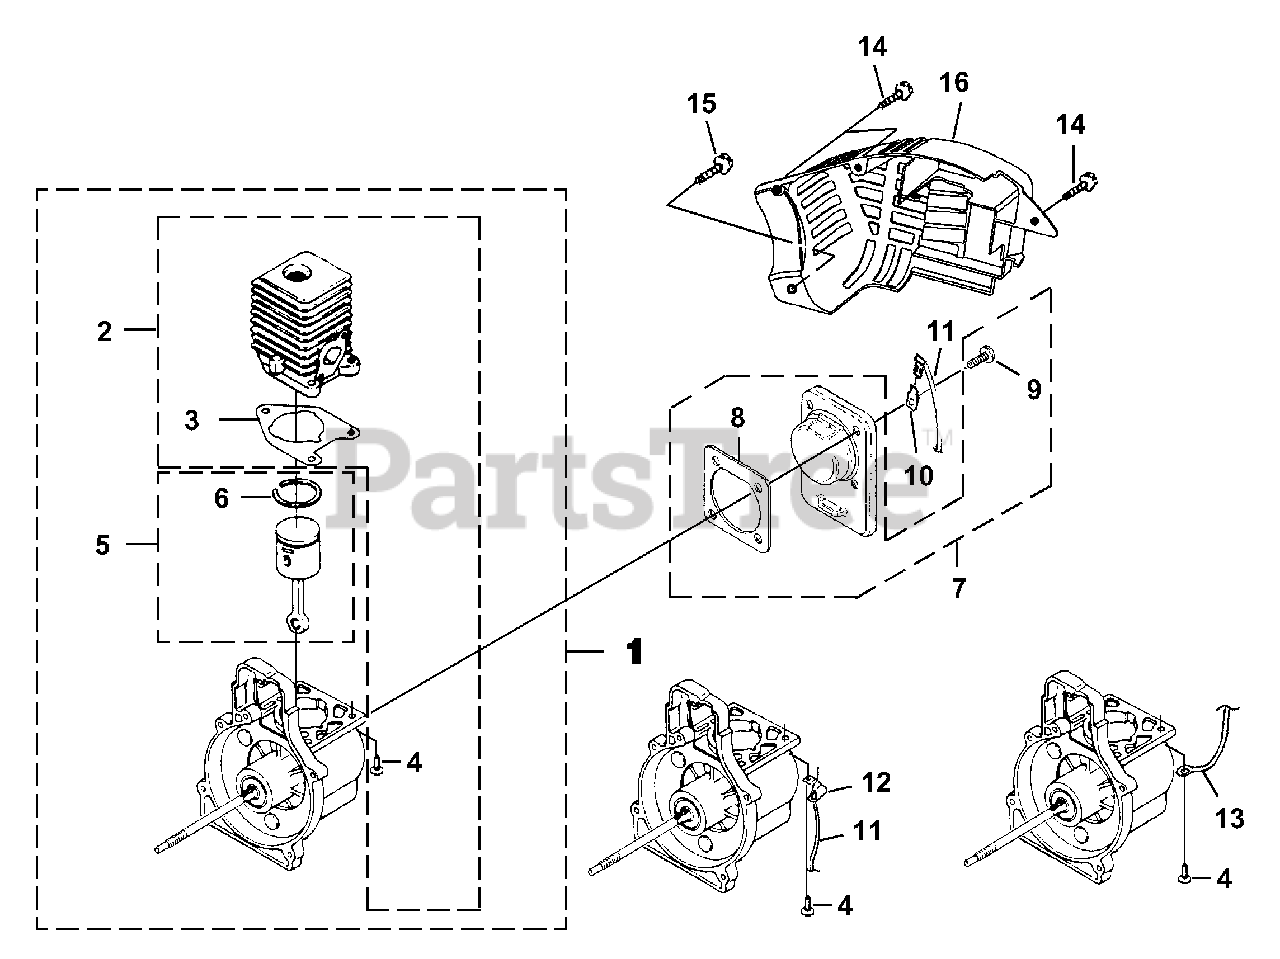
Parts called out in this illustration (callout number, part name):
1	SHORT BLOCK (25cc)
2	25 CC CYLINDER KIT
3	GASKET-Cylinder
4	SCREW, SEMS (12-24 x 3/4)
5	25 CC PISTON & ROD
6	RING-Piston
7	CRANKCASE COVER-Stamped Steel
8	GASKET-Crankcase
9	SCREW, SEMS (10-24 x .56)
10	TAB-Male
11	CABLE-Throttle w/Ignition Leads (Back Packer)
12	CABLE BRACKET (Back Packer)
13	Lead-Ground to Switch (Yard Sweeper)
14	SCREW-Thread Form. (#8 X 1/2")
15	SCREW-Thread Form. (#10 X 3/4")
